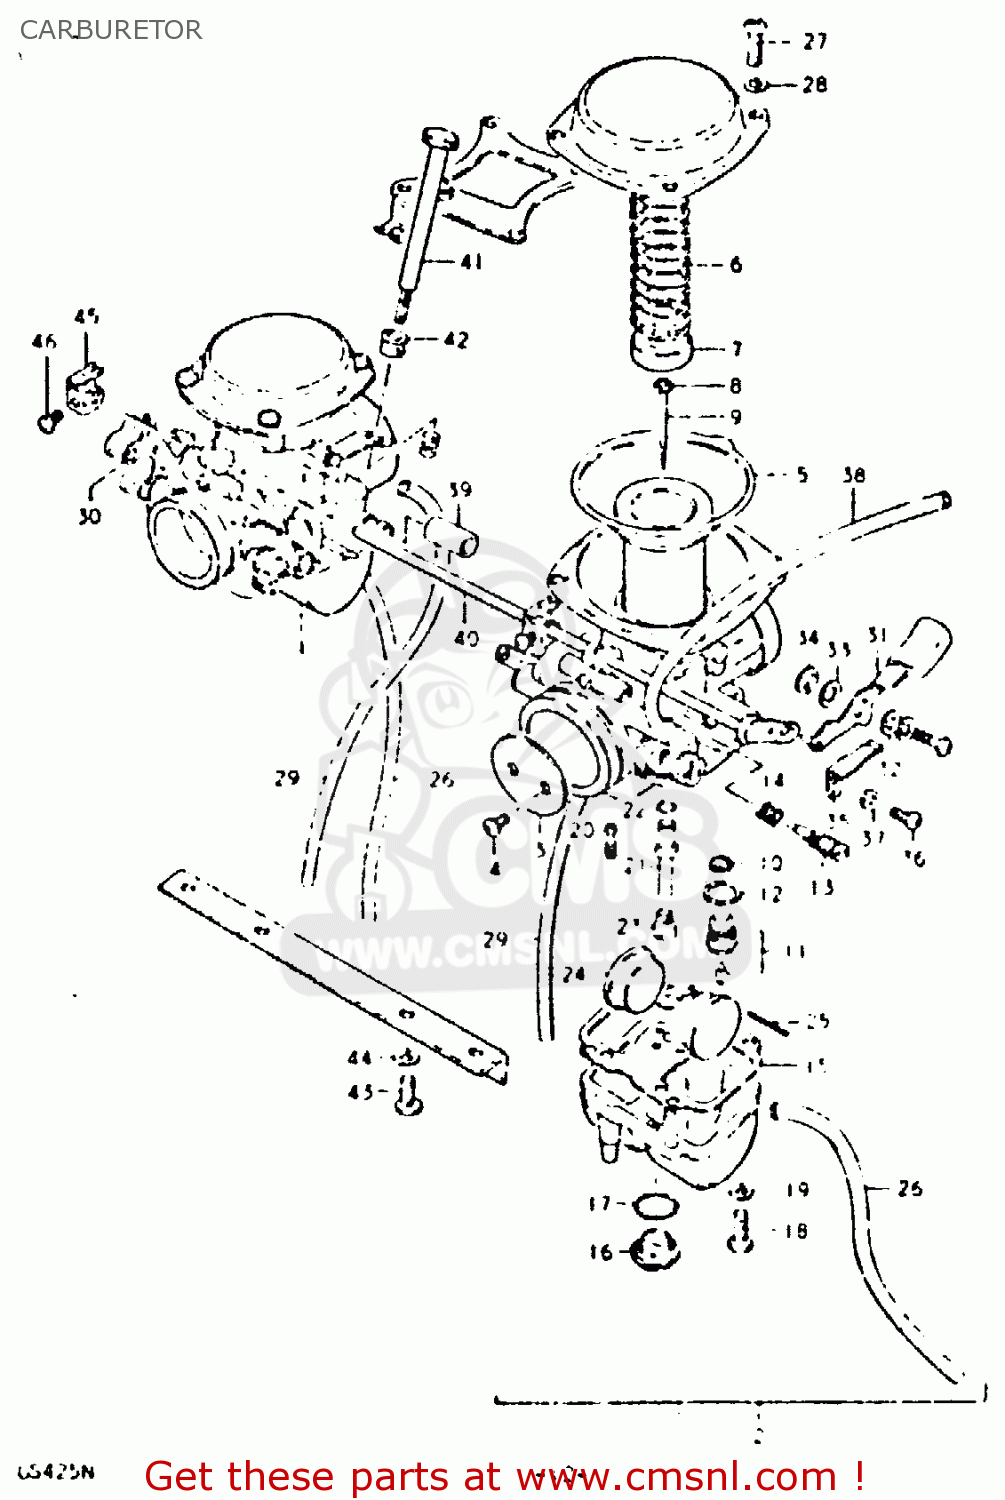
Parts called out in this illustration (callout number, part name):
1	CARBURETOR ASSY, RH
2	CARBURETOR ASSY, LH
3	VALVE,THROTTLE
4	SCREW
5	DIAPHRAGM ASSY
6	SPRING,DIAPHRAGM
7	CONNECTOR
8	CLIP
9	NEEDLE,JET
10	FILTER
11	VALVE ASSY,NEEDLE
12	GASKET,MAIN JET HOLDER (NAS)
13	SCREW,PILOT AIR
14	SPRING,THROTTLE SCREW
15	GASKET,FLOAT CHAMBER (NAS)
16	SCREW,GUIDE
17	O-RING
18	SCREW
19	LOCK WASHER
20	JET,PILOT
21	JET,NEEDLE
22	O-RING
23	SET, MAIN
24	FLOAT
25	PIN,FLOAT
26	HOSE
27	SCREW
28	LOCK WASHER
29	HOSE
30	GASKET
31	LEVER
32	WASHER,STARTER LEVER
33	WASHER,STARTER LEVER
34	RING,STARTER LEVER
35	SPRING
36	SCREW
37	LOCK WASHER
38	HOSE
39	HOSE
40	SHAFT,STARTER
41	ADJUSTER
42	BUSH
43	SCREW 6X12
44	LOCK WASHER
45	LEVER, STARTER
46	SCREW
